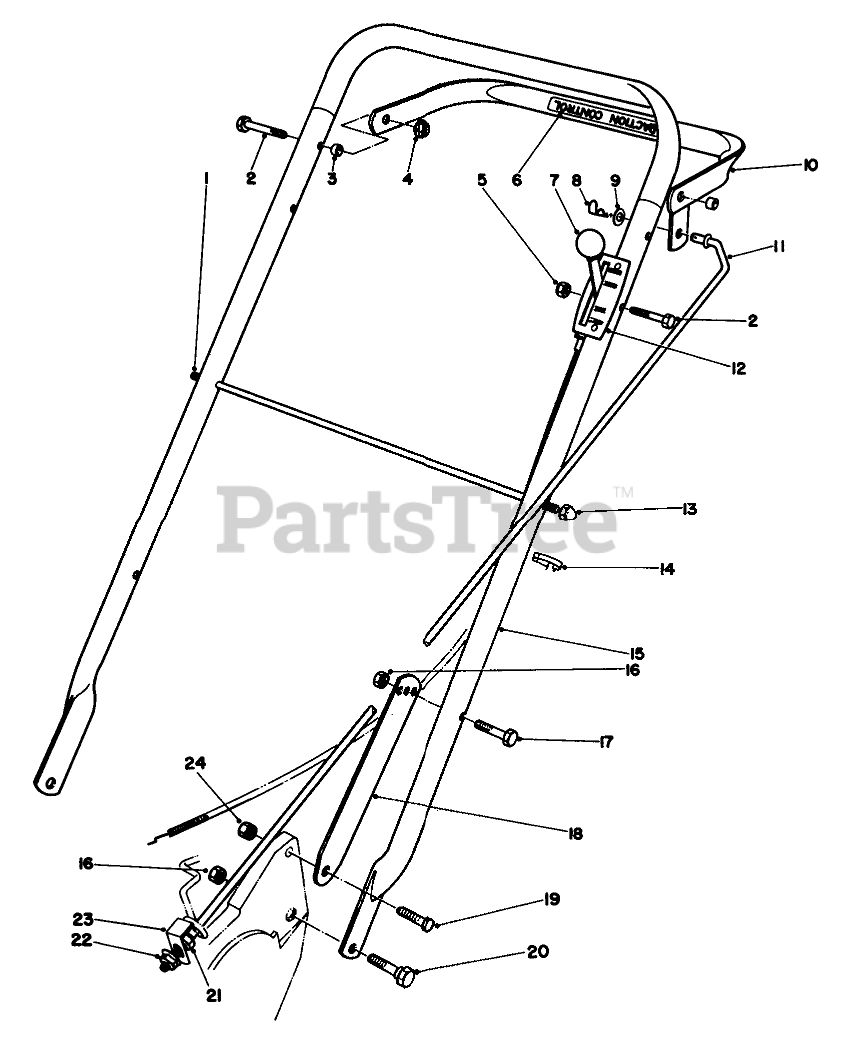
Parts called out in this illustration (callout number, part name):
1	ROD-SUPPORT, BAG
2	SCREW-HH
3	STANDOFF LIFT BAIL
4	NUT-LOCK, HHF
5	NUT-LOCK, NI
6	TRACTION DECAL
7	KNOB-CONTROL
8	PIN-COTTER
9	WASHER-PLAIN
10	CONTROL BAIL ASM
11	CONTROL ROD
12	THROTTLE CONTROL
13	NUT-CAP
15	Handle
16	NUT-LOCK, CONE
17	SCREW-HH
18	Latch-Handle
19	SCREW-HH
20	SCREW-SHOULDER
21	LOCKNUT
22	NUT-FLANGE
23	ROD STOP BRACKET
24	NUT-LOCK, NI
